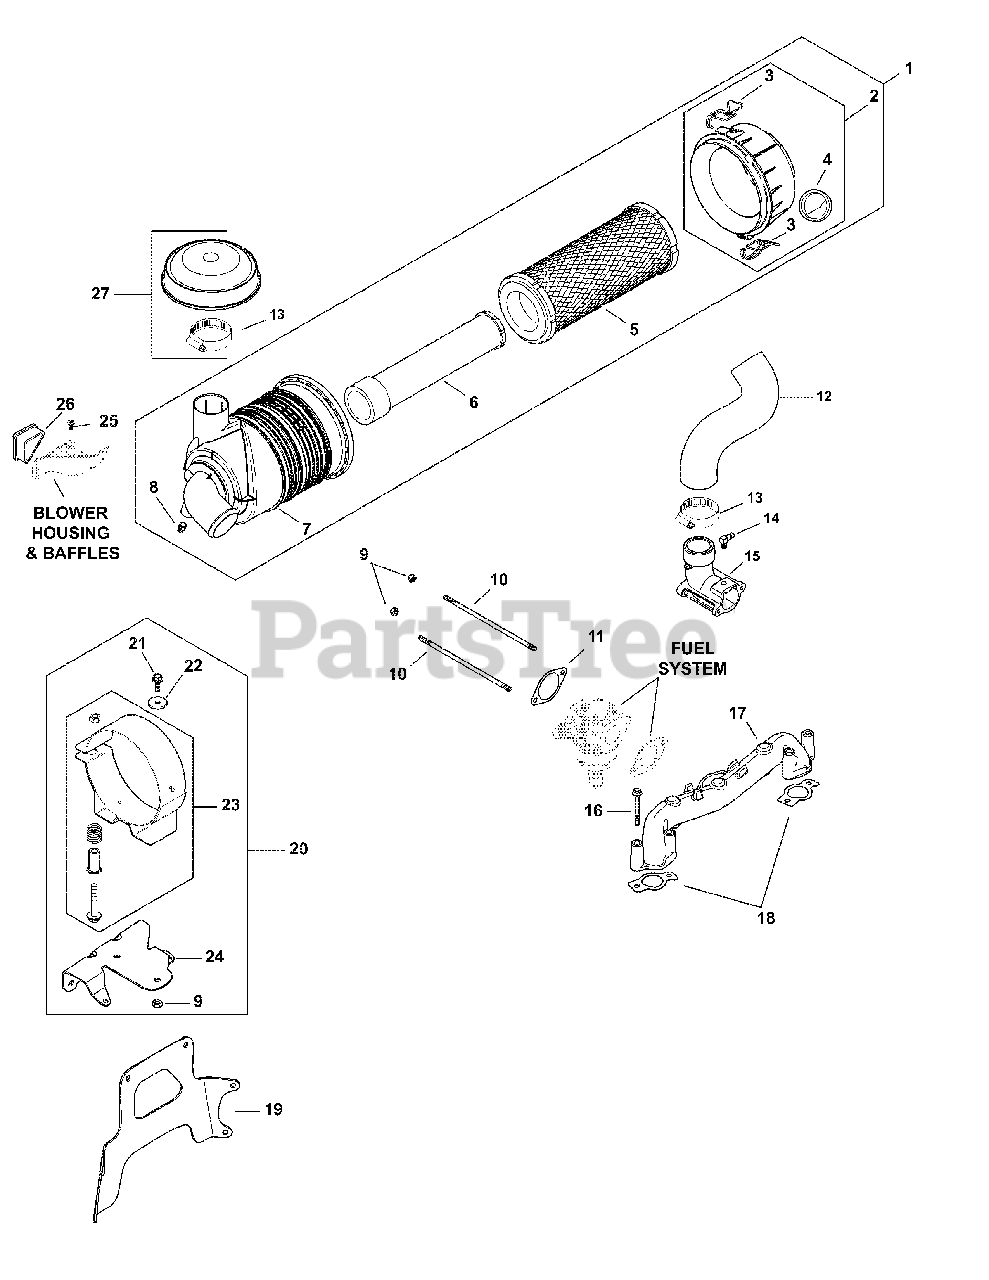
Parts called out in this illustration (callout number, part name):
1	Cleaner, Air-Canister
2	Cover Assembly, Air Cleaner
3	Clip
4	Valve, Dust Ejector
5	Element, Air Filter-Primary
6	Element, Air Filter-Safety
7	Housing, HD Air Cleaner
9	Nut, Lock M6 x 1.0
10	Stud, M6x1.0x180
11	Gasket, Air Cleaner Base
12	Hose, Air Cleaner
14	Connector, Hose
15	Elbow, Air Cleaner
16	Screw, Flg M6x1.0x55
17	Manifold, Intake
18	Gasket, Intake Manifold
19	Bracket, Main Support
20	Bracket, Air Cleaner Sub Assy
21	Screw, Flg M6x1.0x16
22	Washer, Flat 1/4"
23	Bracket Assy, Air Cleaner
24	Bracket, Air Cleaner Mounting
25	Screw, Wsh Hd Tap #8-18x1/2"
26	Cover, Blower Housing
27	Hood, Air Cleaner
